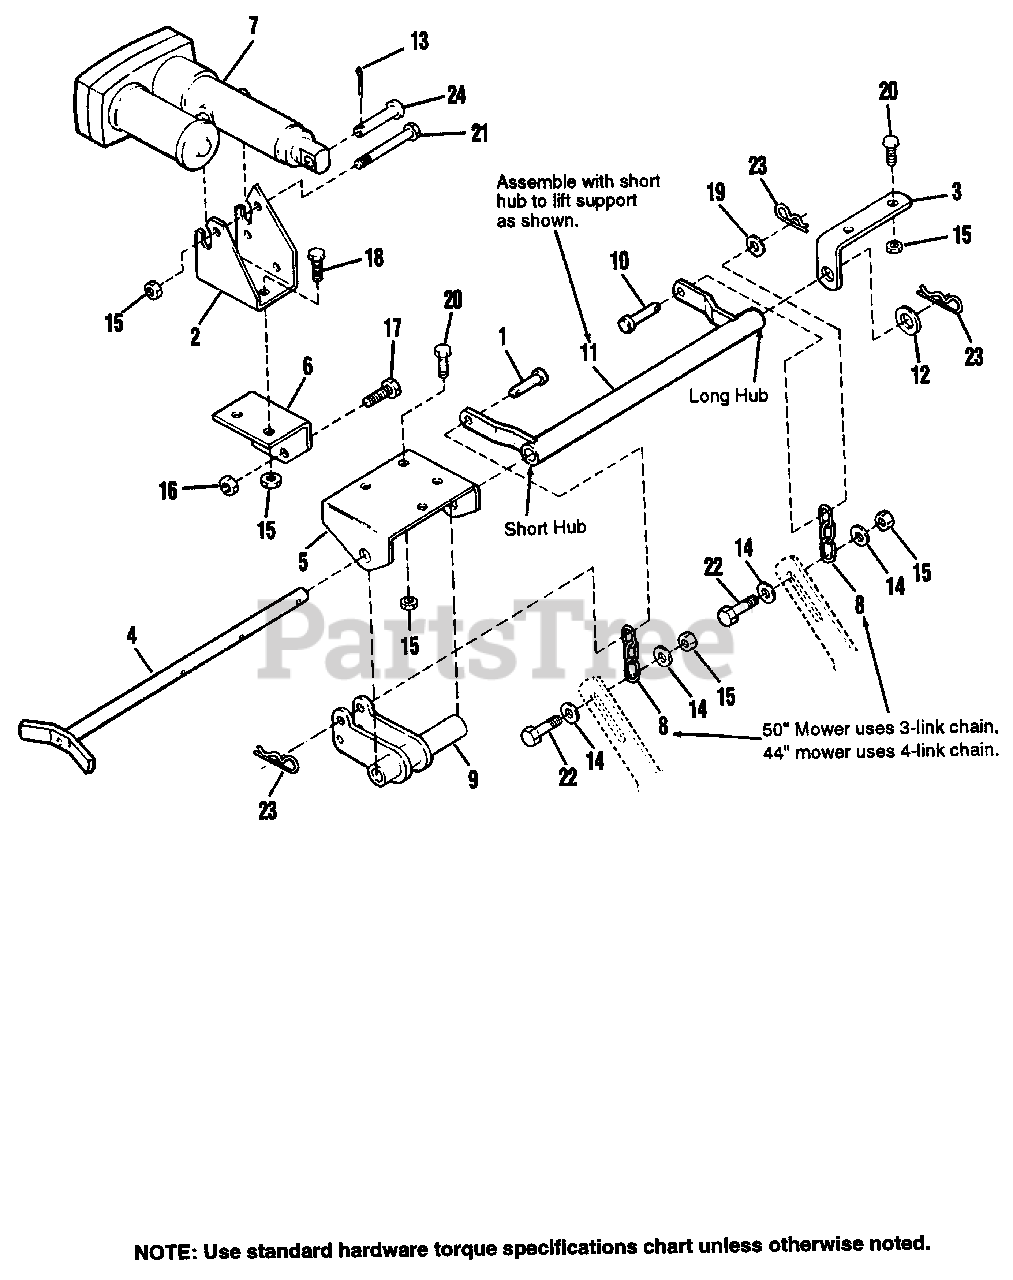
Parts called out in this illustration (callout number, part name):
1	PIN, Clevis
2	BRACKET, Actuator
3	LIFT, Pivot Bracket
4	SHAFT ASSY.
5	SUPPORT, Lift
6	SUPPORT, Actuator
7	POWER LIFT ASSY.
8	CHAIN, 3-Link
8	CHAIN, 4-Link
9	LIFT ARM ASSY.
10	PIN, Clevis
11	LIFT TUBE ASSY.
12	WASHER, Plain
13	PIN, Cotter
14	WASHER, Plain
15	NUT, Hex, Lock, ESNA, 5/16-18
16	NUT, Hex, Lock, ESNA, 3/8-16
17	CAPSCREW, Hex Hd., Whizlock, 3/8-16 x 1
18	CAPSCREW, Hex Hd., 5/16-18 x 1
19	WASHER, Plain
20	CAPSCREW, Hex Hd., 5/16-18 x 7/8
21	CAPSCREW, Hex Hd., 5/16-18 x 3-1/4
22	CAPSCREW, Hex Hd., 5/16-18 x 1-1/2
23	CLIP, Hair Pin (Large)
24	PIN
